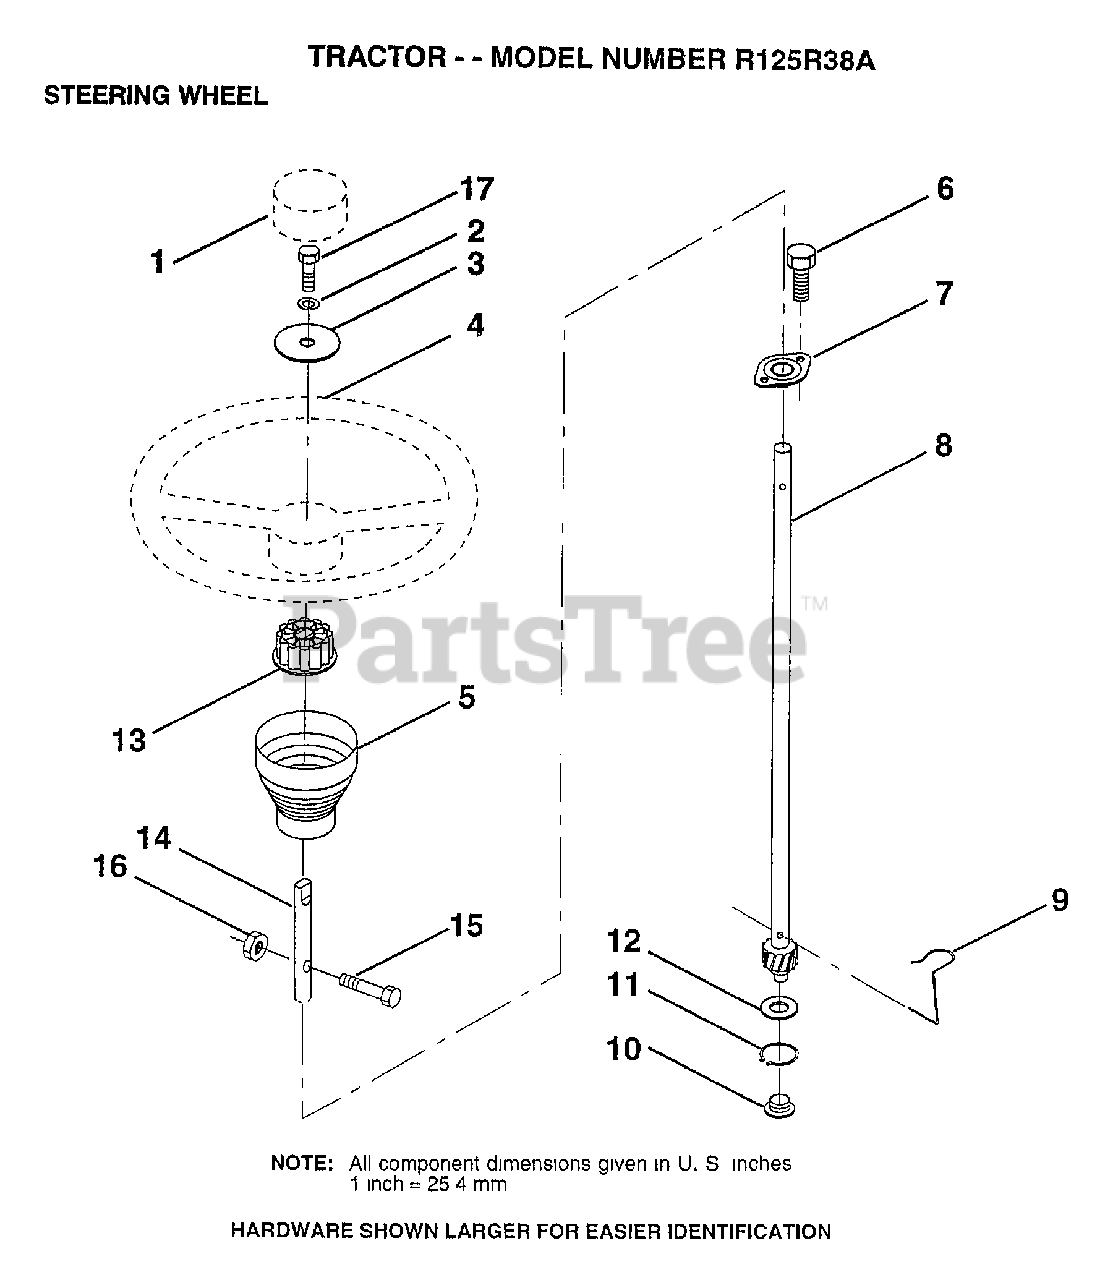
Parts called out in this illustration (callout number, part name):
1	ST WHL INSERT CAP
2	LOCKWASHER
3	WASHER T
5	SLEEVE STEERING
6	"SCREW-TT,10-32 FL"
7	BUSHING.STR.623
8	SHAFT.STEERING.LR
9	CLIP, STEERING
10	BUSHING, LOWER, STEERING
11	RING
12	WASHER LT
13	ADAPTER LT
14	EXT SHAFT STEERIN
15	BOLT
16	NUT
17	BOLT
